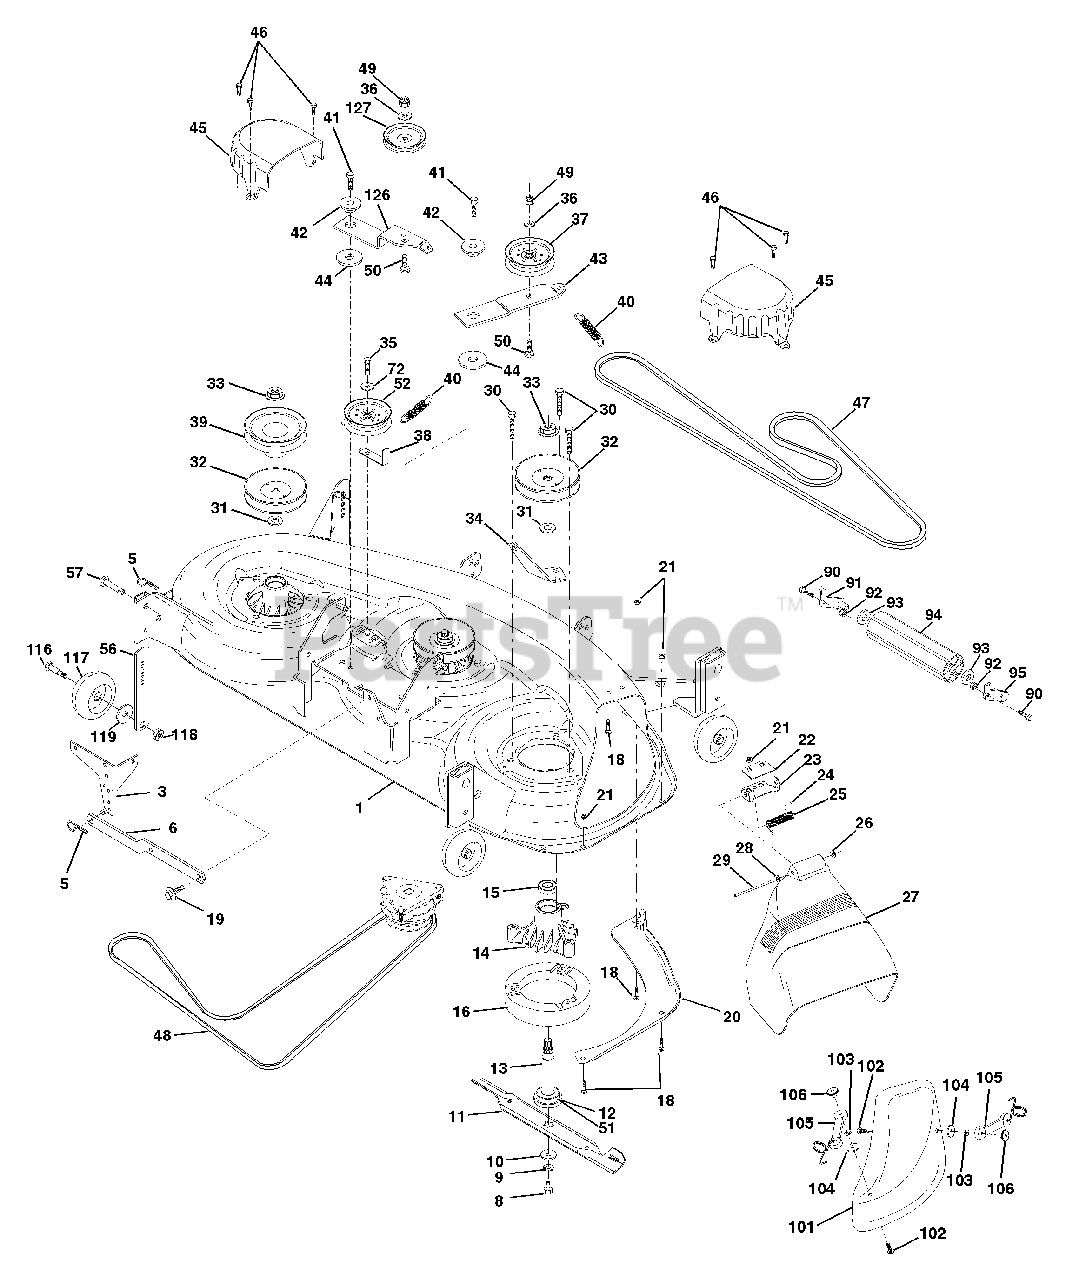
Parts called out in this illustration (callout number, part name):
1	Deck Asm., Mower 46"
3	Bracket Asm., Sway Bar
5	Retainer Spring
6	Arm, Suspension, Rear (Sway Bar)
8	Bolt, Patched 3/8-24 x 1-1/4 Gr. 8
9	Washer, Lock Hvy., Unplated 3/8
10	Washer, Hard Blade, Mower Vented
11	Blade, 46" Mulching
12	Bearing, Ball, Mandrel #6204
13	Shaft Asm. w/Lower Bearing
14	Housing, Mandrel
15	Bearing, Ball, Mandrel
16	Stripper, Mower Round
18	Bolt, Carriage 5/16-18 x 5/8
19	Bolt, Hex Head, Shoulder 5/16-18
20	Baffle, Vortex Mower 46"
21	Nut, Crownlock 5/16-18 UNC
22	Stiffiner, Bracket
23	Bracket, Deflector
24	Cap, Sleeve
25	Spring, Torsion, Deflector
27	Shield, Deflector Mower
28	Washer 11/32 x 5/8 x 16 Ga.
29	Rod, Hinge
30	Screw, Thdroll Washer Hd
31	Washer, Spacer Mower Vented
32	Pulley, Mandrel
33	Nut, Flg. Top Lock Cntr. 9/16
34	Anchor, Spring Deck 46"
35	Screw, Thdroll 3/8-16 x 1-3/4 Tytt
36	Washer 13/32 x 13/16 x 16 Ga.
37	Pulley, Idler, Flat
38	Keeper, Belt, Idler
39	Pulley, Idler, Driven
40	Spring, Secondary 44/46/50 Vent
41	Screw, Thdroll 3/8-16 x 1-1/4 Tytt
42	Spacer, Retainer
43	Arm, Idler Secondary
44	Washer, Hardened
45	Cover, Mandrel Deck
46	Screw, Thdroll. 1/4-20 x 5/8
47	V-Belt, Mower, Secondary
48	V-Belt, Mower, Primary
49	Nut, Crownlock 3/8-16 UNC
50	Bolt, Carriage 3/8-16 x 1-1/2 Gr. 5
51	Washer Felt
52	Pulley Idler Flat 46 PRI drive
56	Bar Pnt Adjusting Wheel Gauge
57	Pin Head Rivet
72	Washer 13/32 x 16 Ga.
90	Bolt Fin Hex 3/8-16 x 1
91	Bracket Asm Noseroller LH
92	Nut Lock Hex W/Ins 3/8-16 UNC
93	Washer 17/32 x 7/8 x 16 Ga.
94	Roller Nose
95	Bracket Asm Noseroller RH
101	Cover, Mulching
102	Screw
103	Washer, Lock #10
105	Latch Asm. Mulch/Bagger
106	Nut, Weld
116	Bolt, Shoulder
117	Gauge Wheel, Wide
118	Nut, Centerlock 3/8-16 UNC
119	Washer 3/8 x 7/8 x 14 Ga.
126	Arm, Idler, Primary Deck 46"
127	Pulley, Idler, V-Groove Dim. 4.25
